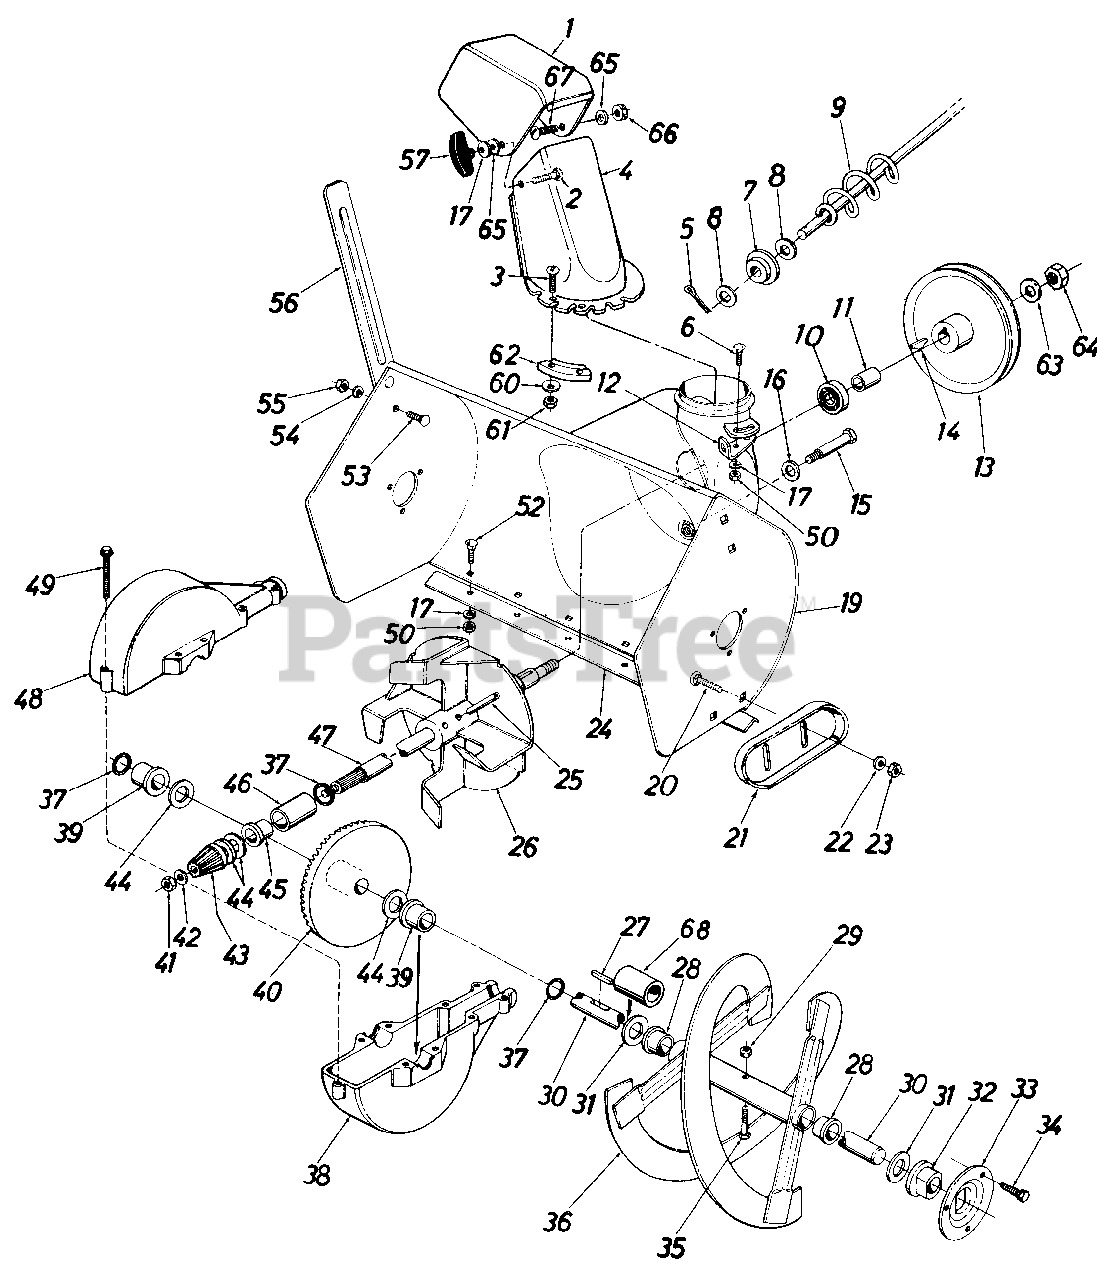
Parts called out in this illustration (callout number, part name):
1	Upper Chute
2	Carriage Bolt 5/16-18 x 1.0"
3	Truss Mach. Scr. 1/4-20 x .75"
4	Lower Chute
5	Cotter Pin
6	Carriage Bolt 5/16-18 x .75"
7	Bushing
8	Fl-Wash. .385 I.D. x .62" O.D.
9	Chute Crank Ass'y.
10	Ball Brg. .62" I.D x 1.38" O.D
11	Spacer .63" I.D. x .88" O.D. x.900" Lg.
13	1/2" "V"-Pulley .625" I.D. x 7.50" O.D. (440, 450, 550 & 552)
14	#61 Hi-Pro Key 3/16" x 5/8" Dia.
15	Shld. Bolt .50" Dia. x 2.11
16	Bell-Wash. .40" I.D. x .88" O.D. x .06
17	Bell-Wash. .34" I.D. x .88" O.D.
20	Carriage Bolt 3/8-16 x .62
21	Slide Shoe
22	Bell-Wash. 3/8" I.D.
23	Hex Jam Nut 3/8-16 Thd.
24	20" Shave Plate (420)
26	11" Dia. Blower Fan Ass'y.
27	Sq. Key 3/16" x 1.5" Lg.
28	Flange Brg. .75" I.D. x .88" O.D.
29	Hex Ins. L-Nut 5/16-18
30	Spiral Axle (420)
31	Fl-Wash. .75" I.D. x 1.50" O.D. x .06
32	Flange Brg. w/Flats .755" I.D.
33	Bearing Housing
34	Hex Wash. Hd. Self-Tap Scr. 5/16-24 x .62" Lg.
35	Hex Bolt 5/16-18 x 1.50" Lg.
36	20" Spiral Ass'y.-L.H. (420)
37	"O"-Ring-3/4" I.D.
38	Bevel Gear Housing-Lower Half
39	Plastic Flange Brg. .755" I.D.
40	Bevel Gear
41	Hex Cent. L-Nut 5/16-24 Thd.
42	Fl-Wash. .34" I.D. x .62" O.D. x .06
43	Pinion Gear
44	Fl-Wash. .75" I.D. x 1.25" O.D. x .06
45	Flange Brg. .755" I.D.
46	Sleeve Brg. .755" I.D.
47	Blower Axle
48	Bevel Gear Housing- Upper Half
49	Hex Wash. Hd. Self-Tap Scr. 1/4-20 x 1.00" Lg.
50	Hex Nut 5/16-18 Thd.*
52	Carriage Bolt 5/16-18 x .62" Lg.
53	Carriage Bolt 5/16-18 x .62" Lg.
54	L-Wash. 5/16" I.D.
55	Hex Nut 5/16-18 Thd
56	Drift Cutter Bar
57	Knob
60	Fl-Wash. 1/4" I.D.
61	Hex L-Nut 1/4-20 Thd.
62	Chute Flange Keeper
63	Fl-Wash. .64" I.D. x .941' O.D. x .06
64	Hex Jam Nut 5/8-18 Thd.
65	Fl-Wash. .344 I.D. x 1.125 O.D.
66	Hex L-Nut 5/16-18 Thd.
67	Truss Mach. Scr. 5/16-18 x .75" Lg.
68	Spacer (826)
